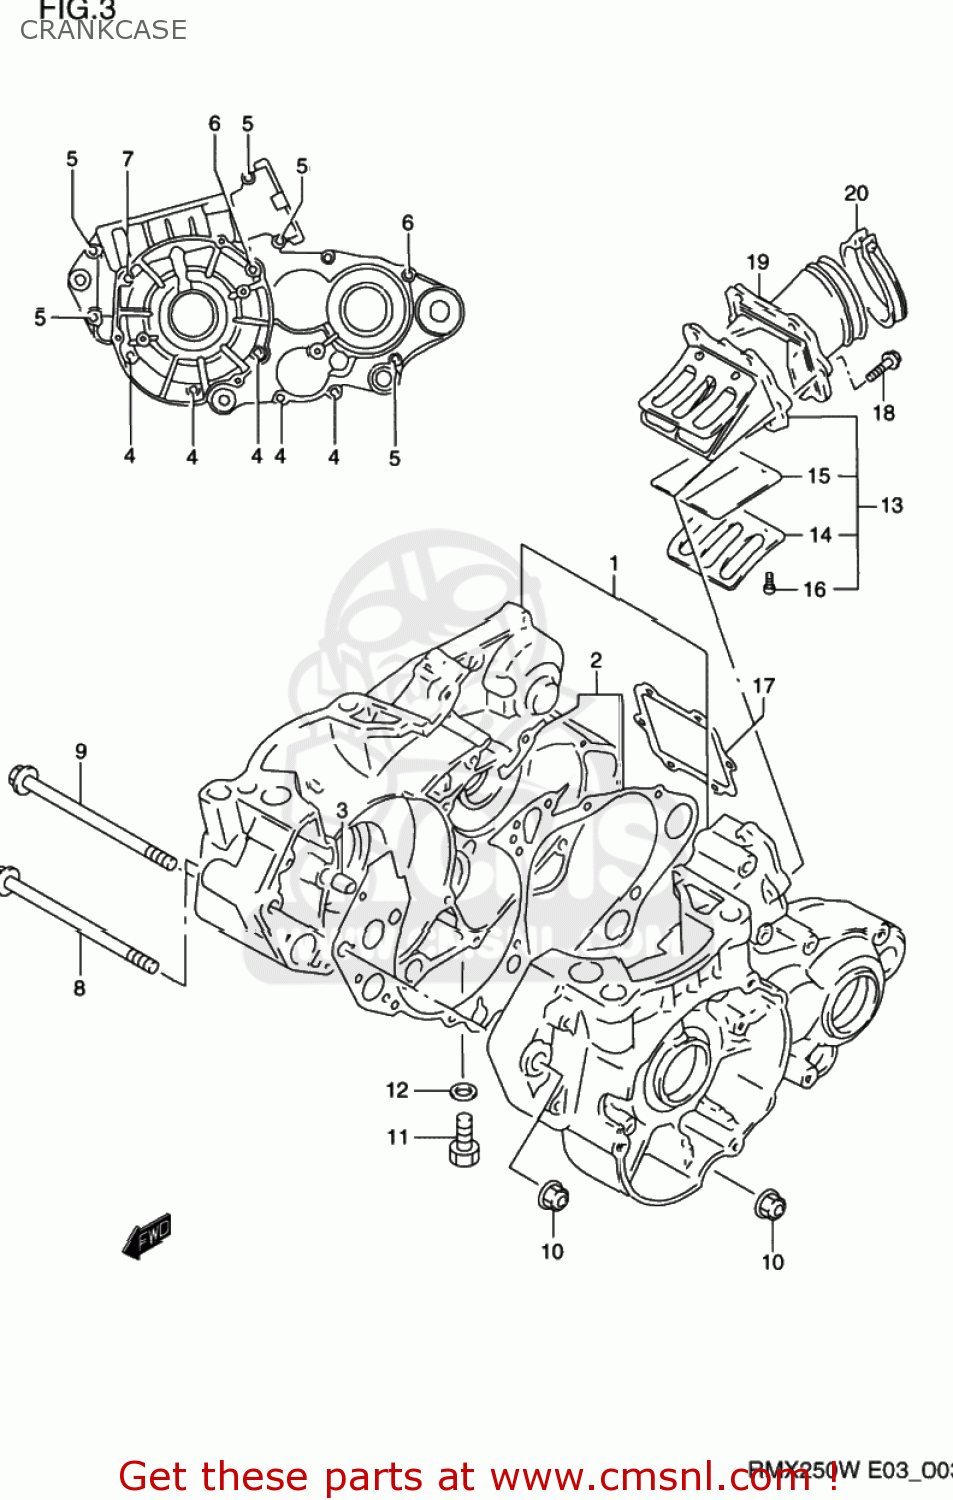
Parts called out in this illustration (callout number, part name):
1	CRANKCASE SET
2	GASKET,CRANKCASE (NAS)
3	PIN
4	BOLT
5	BOLT
6	BOLT
7	BOLT
8	BOLT(8X102)
9	BOLT(8X137)
10	NUT
11	BOLT
12	GASKET(8.2X14X1) (NAS)
13	VALVE ASSY,REED
14	STOPPER,REED VALVE
15	VALVE,REED
16	SCREW
17	GASKET,REED VALVE (NAS)
18	SCREW
19	PIPE,INTAKE
20	CLAMP
